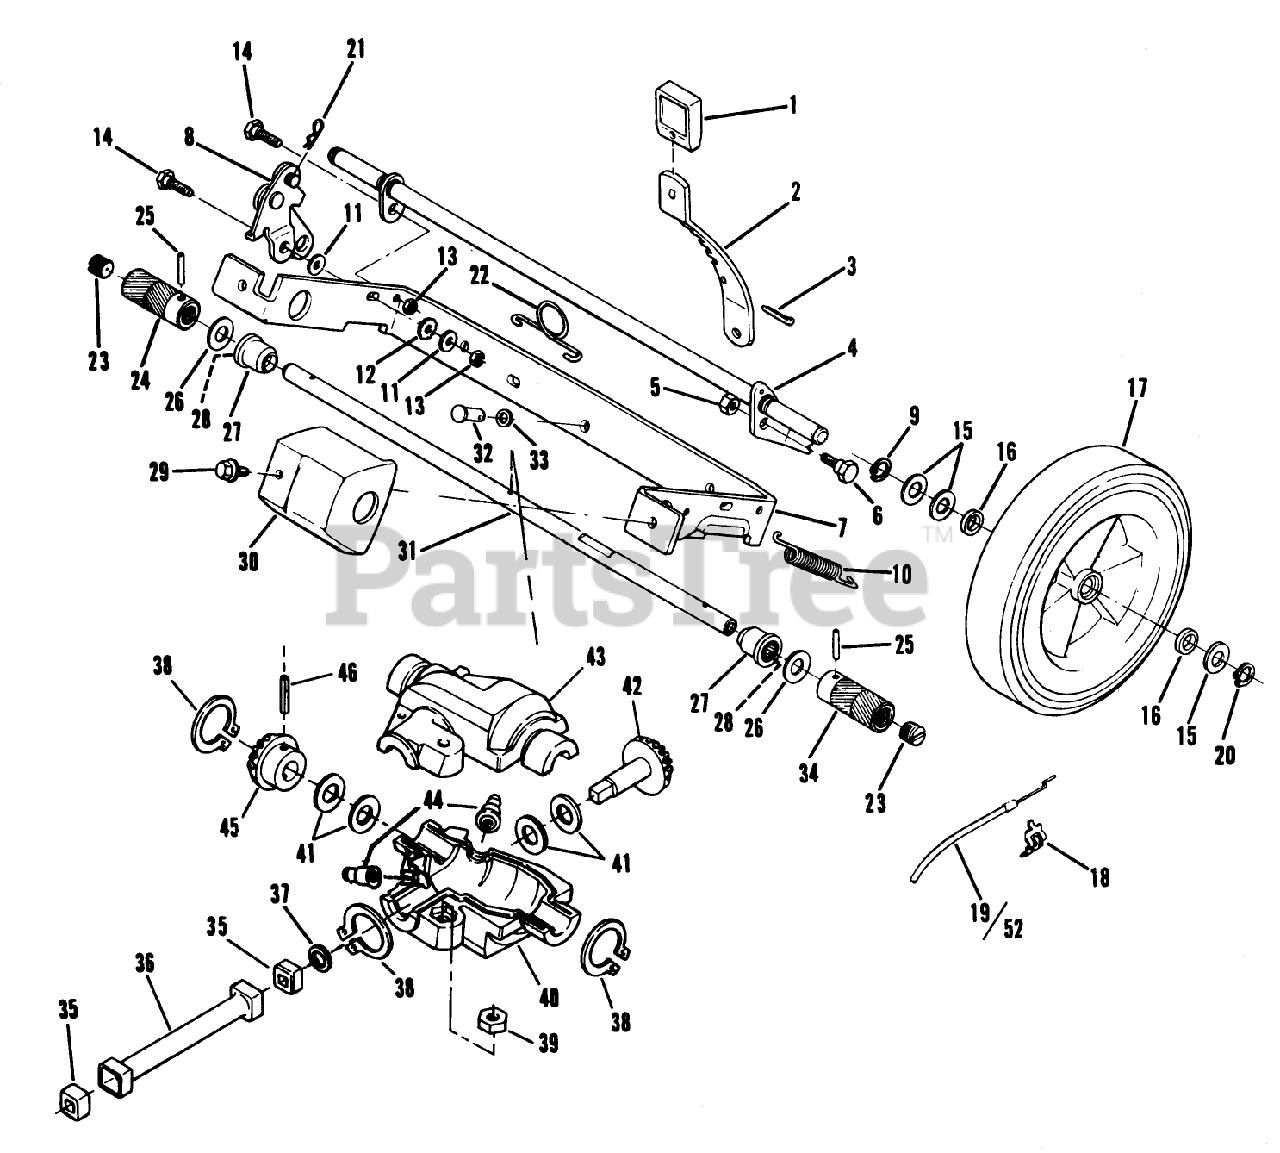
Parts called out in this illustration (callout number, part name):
5	LOCKNUT E
6	BOLT RB&W
7	Bracket-21" Axle
9	RET RING
10	SPRING
11	WASHER S
13	STOP NUT
14	BOLT RB&W
15	SPACER
20	RET RING
22	SPRING N.A.S
23	GREASE PLUG
28	BEARING AY F
31	DRIVE SHFT TAG AY
33	WASHER SPRING LAR
35	BUSHING
39	LOCKNUT E
41	THRUST WASHER
44	ZERK FITTING
46	ROLL PIN
